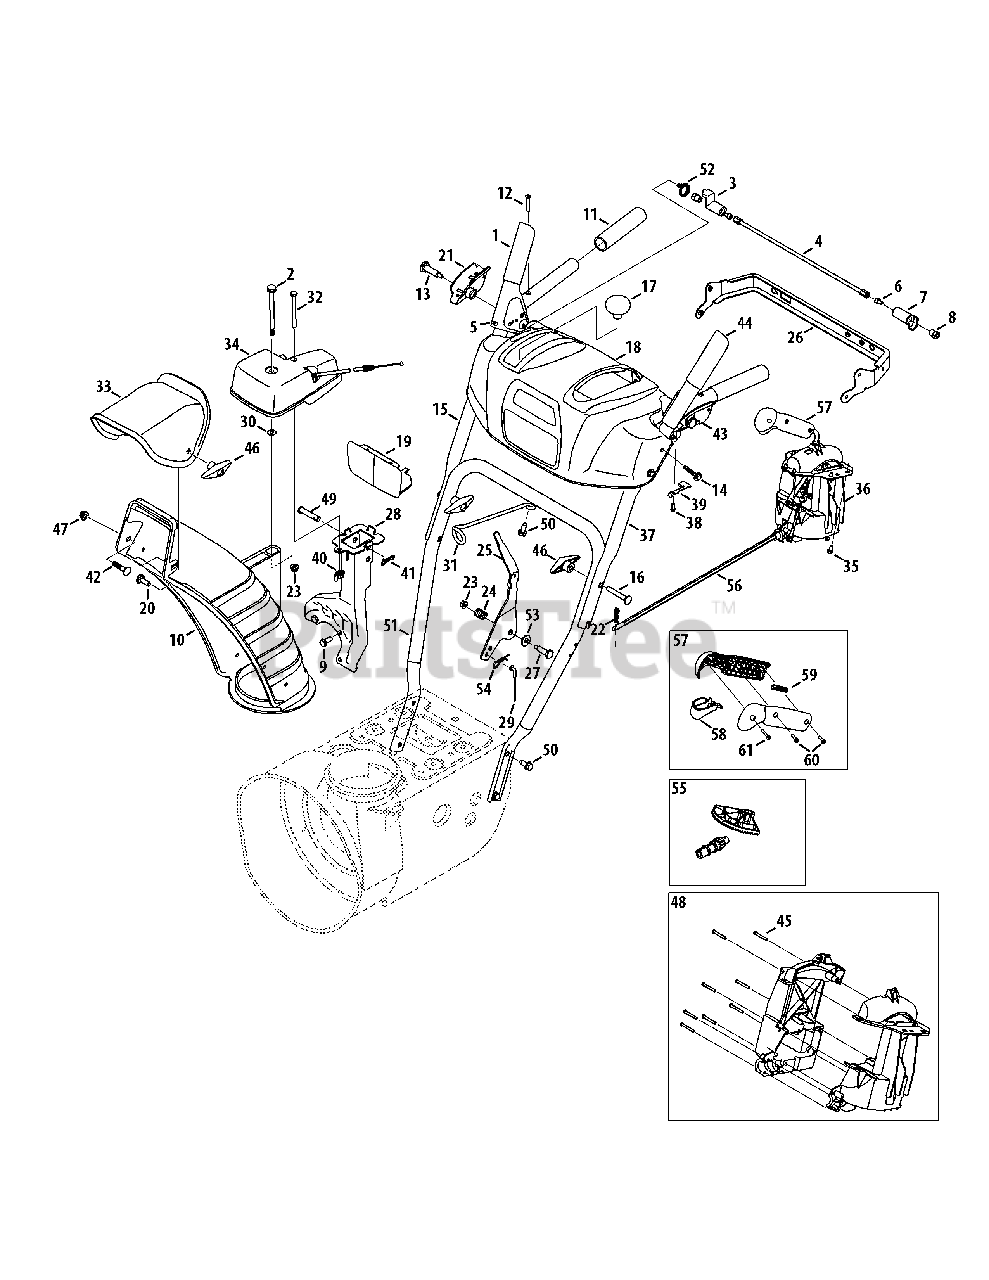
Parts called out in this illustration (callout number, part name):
1	Handle Engagement Ass’y RH
2	Flange Shoulder Screw
3	Lock Plate
4	Pivot Rod
5	Rubber Bumper
6	Screw, 1/4-20 x .500
7	Clutch Lock Cam
8	Shoulder Nut, 1/4-20
9	Hex Screw, 5/16-24 x .750
10	Lower Chute
11	Handle Grip
12	Screw, #10-24 x 0.375
13	Shoulder Screw, 1/4-20
14	Screw, 1/4-20 x 1.625
15	Upper Handle RH
16	Carriage Screw, 5/16-18 x 2.25
17	Shift Knob
18	Handle Panel
20	Carriage Bolt, 5/16-18 x 1.0
21	Handle Clutch Lock RH Assy
22	Cotter Pin
23	Flange Lock Nut, 1/4-20
24	Compression Spring
25	Shift Lever
26	Panel Bracket
27	Shoulder Screw
28	Chute Support Bracket
29	Speed Selector Cable
30	Flat Washer, .25 x .630 x .0515
31	Cable Guide
32	Hex Screw, 1/4-20 x 3.00
33	Upper Chute
34	Gearbox Assembly
35	Hi-Lo Screw, 1/4-15 x 0.5
36	2-Way Chute Control Assembly
37	Upper Handle LH
38	Screw, #8-16 x 0.50
39	Clutch Lock Spring
40	Wing Nut, 1/4-20
41	Bow Tie Cotter Pin
42	Carriage Bolt, 5/16-18 x .75
43	Handle Clutch Lock LH Assy
44	Handle Engagement Assembly LH
45	Screw, #8-18 x 1.250
46	Wing Knob
47	Flange Lock Nut, 5/16-18
48	Handle Housing Assembly
49	Clevis Pin
50	Screw, 5/16-18 x 0.75
51	Lower Handle
52	Torsion Spring
53	Flat Washer
54	Click Pin
55	Gear Set Assembly
56	Chute Rod
57	Handle Assembly
58	Handle Lever
59	Handle Plunger
60	Screw, Mach., #8-32 x .750
61	Screw, #8 x 1.00
